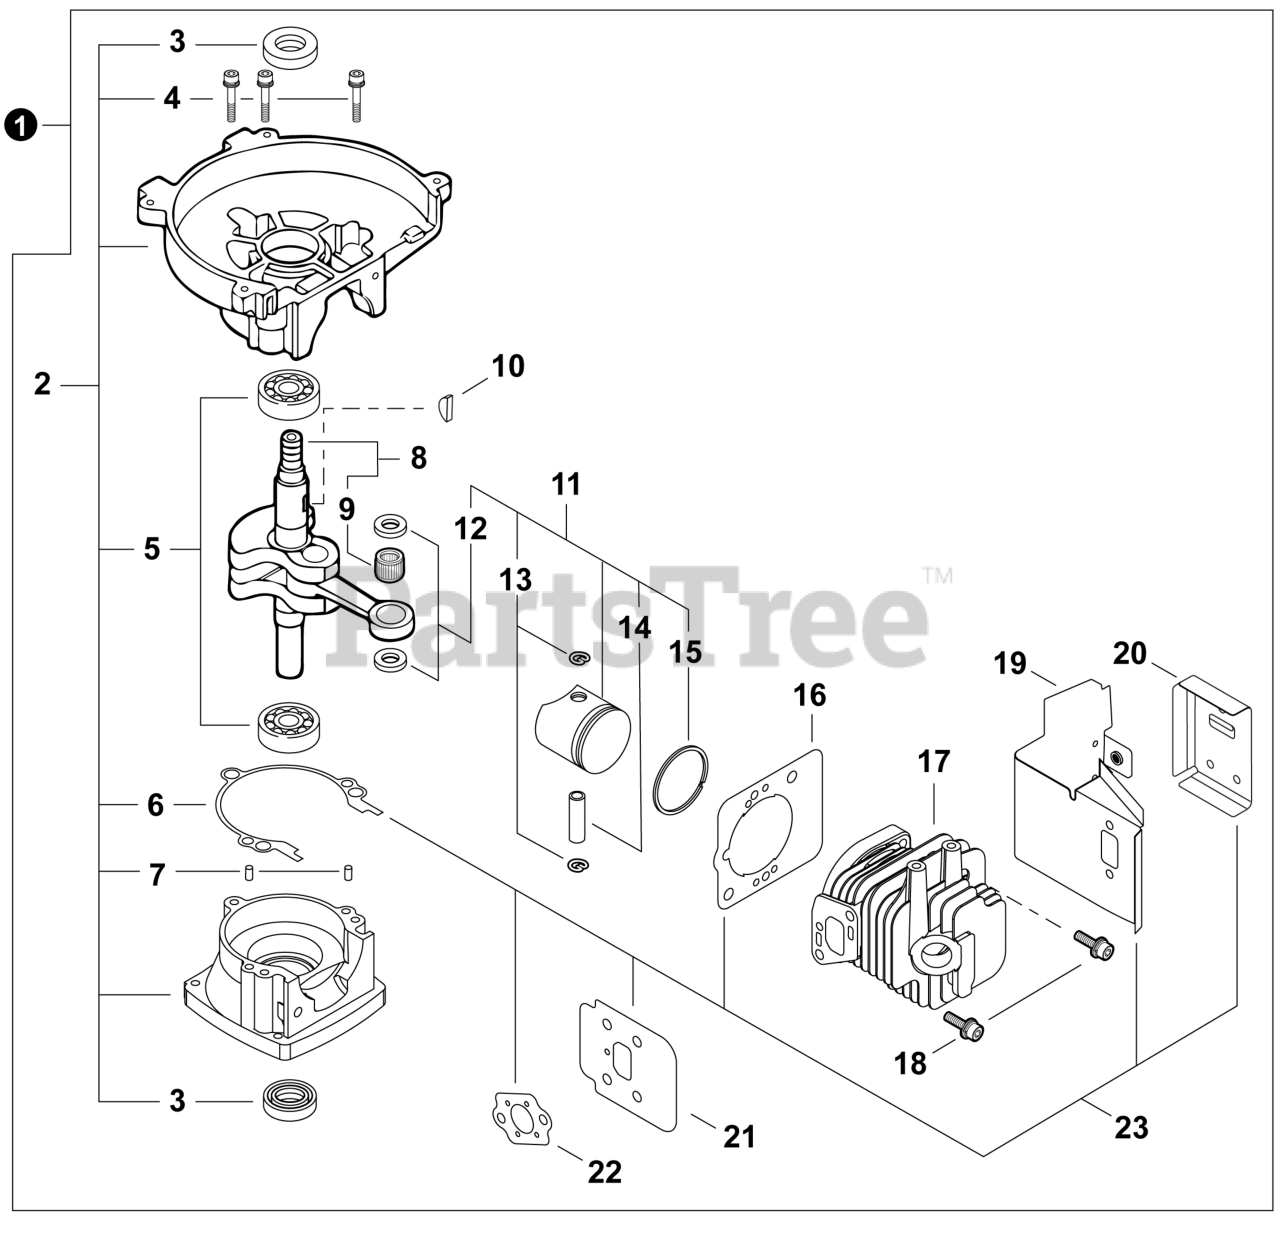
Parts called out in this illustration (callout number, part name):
1	SHORT BLOCK
2	CRANKCASE KIT
3	SEAL, OIL 12
4	BOLT 5x28
5	BEARING, BALL 6201
6	GASKET, CRANKCASE
7	PIN, LOCATING 4x8
8	CRANKSHAFT ASSY
9	BEARING, NEEDLE 8
10	KEY, WOODRUFF
11	PISTON KIT
12	WASHER, THRUST
13	RING, SNAP
14	PIN, PISTON 8
15	RING, PISTON
16	GASKET, CYLINDER
17	CYLINDER
18	BOLT 5x22
19	HEAT SHIELD, EXHAUST
20	GASKET, EXHAUST
21	HEAT SHIELD, INTAKE
22	GASKET, INTAKE
23	GASKET KIT: ENGINE, INTAKE, EXHAUST
